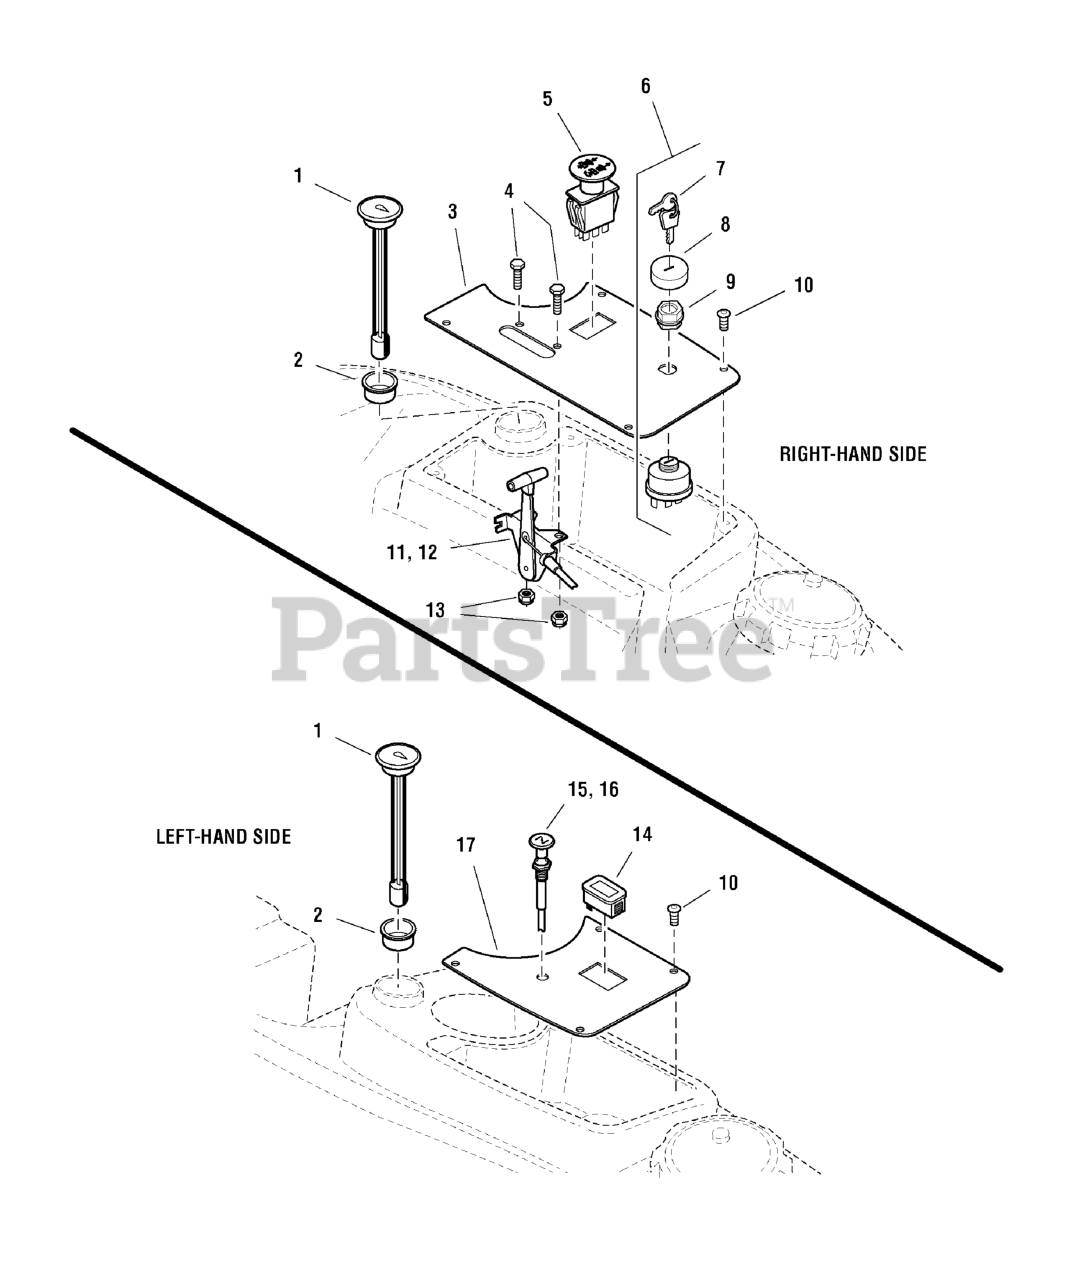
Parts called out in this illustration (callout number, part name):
1	GAUGE, FUEL, 12
2	GROMMET
3	CONTROL PANEL-RH
4	BOLT, 1/4-20 x 3/4
5	SWITCH, BLADE ENGAGEMENT
6	SWITCH, IGNITION, 6 POST
7	KEY, IGNITION MOLDED SET
8	COVER, PLASTIC, SNAP ON
9	PLASTIC NUT
10	SCREW, Allen Head, 1/4-20 x 1/2
11	CABLE, Throttle, 38"
12	CABLE, Throttle, 45"
13	NUT, 1/4-20 HEX SERR. FLANGE
14	HOUR METER
15	CABLE, Choke Control, 39-1/2"
16	CABLE, CHOKE CONTROL, 56
17	CONTROL PANEL-LH
